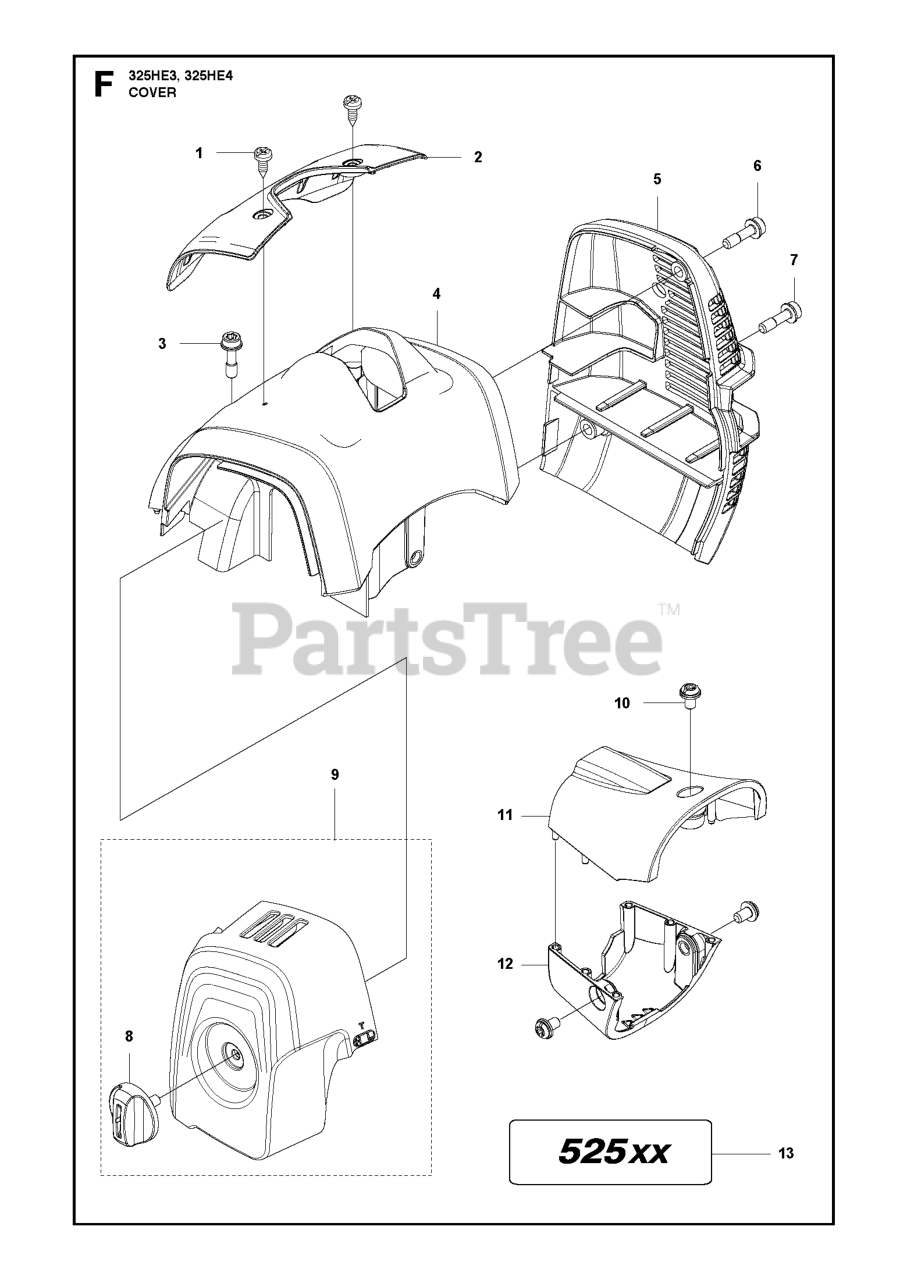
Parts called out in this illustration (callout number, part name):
2	ARM PROTECTION
3	BOLT
4	CYLINDER COVER
4	Cylinder
5	MUFFLER GUARD
6	BOLT
7	BOLT
8	KNOB CLEANER COLOR:GREY
9	FILTER COVER ASSY
11	COVER CLUTCH HOUSING UPPER
11	COVER CLUTCH HOUSING,UPPER
12	COVER CLUTCH HOUSING LOWER
12	COVER CLUTCH HOUSING,LOWER
13	DECAL NAME 525LS
